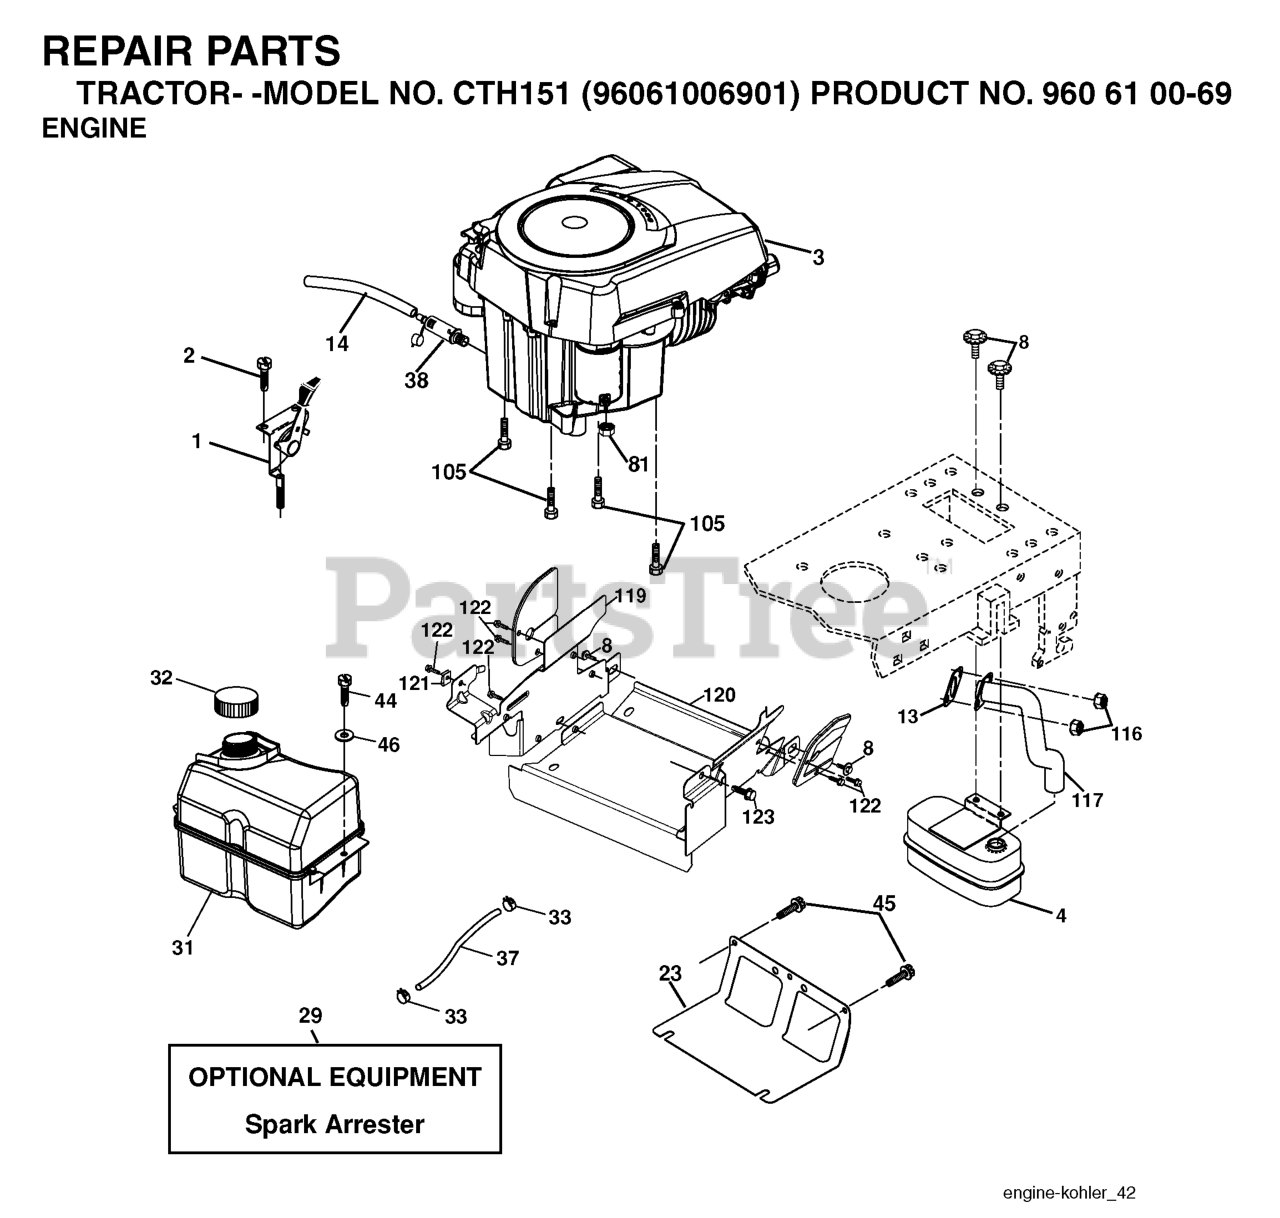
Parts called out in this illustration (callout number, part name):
1	CONTROL.THROTTLE.LT/YT
2	SCREW
4	MUFFLER.SINGLE.CYL.KOHL/B&S
8	BOLT.5/16-18UNCX3/4 W/SEMS.BLK
13	GASKET.EXHAUST.KOHLER
14	TUBE, DRAIN OIL ASM.
23	SHIELD.BROWNING.DBR.GUARD
29	KIT.SPARK ARRESTOR 794945 B&S
31	TANK FUEL
32	FUEL CAP
33	HOSE CLAMP
37	LINE.FUEL.20
38	PLUG DRAIN OIL EASY
44	SCREW HEXWSHR 1/4-20X3/4
45	SCREW, 3/8-16X3/4
81	NUT
105	SCREW 3/8-16X1
116	NUT.HEX.FLANGE.TOPLOCK
117	RP.TUBE.EXHAUST.KOHL.COURAGE
122	SCREW.1/4-20X5/8
123	SCREW, 5/16-18 X 1/2
